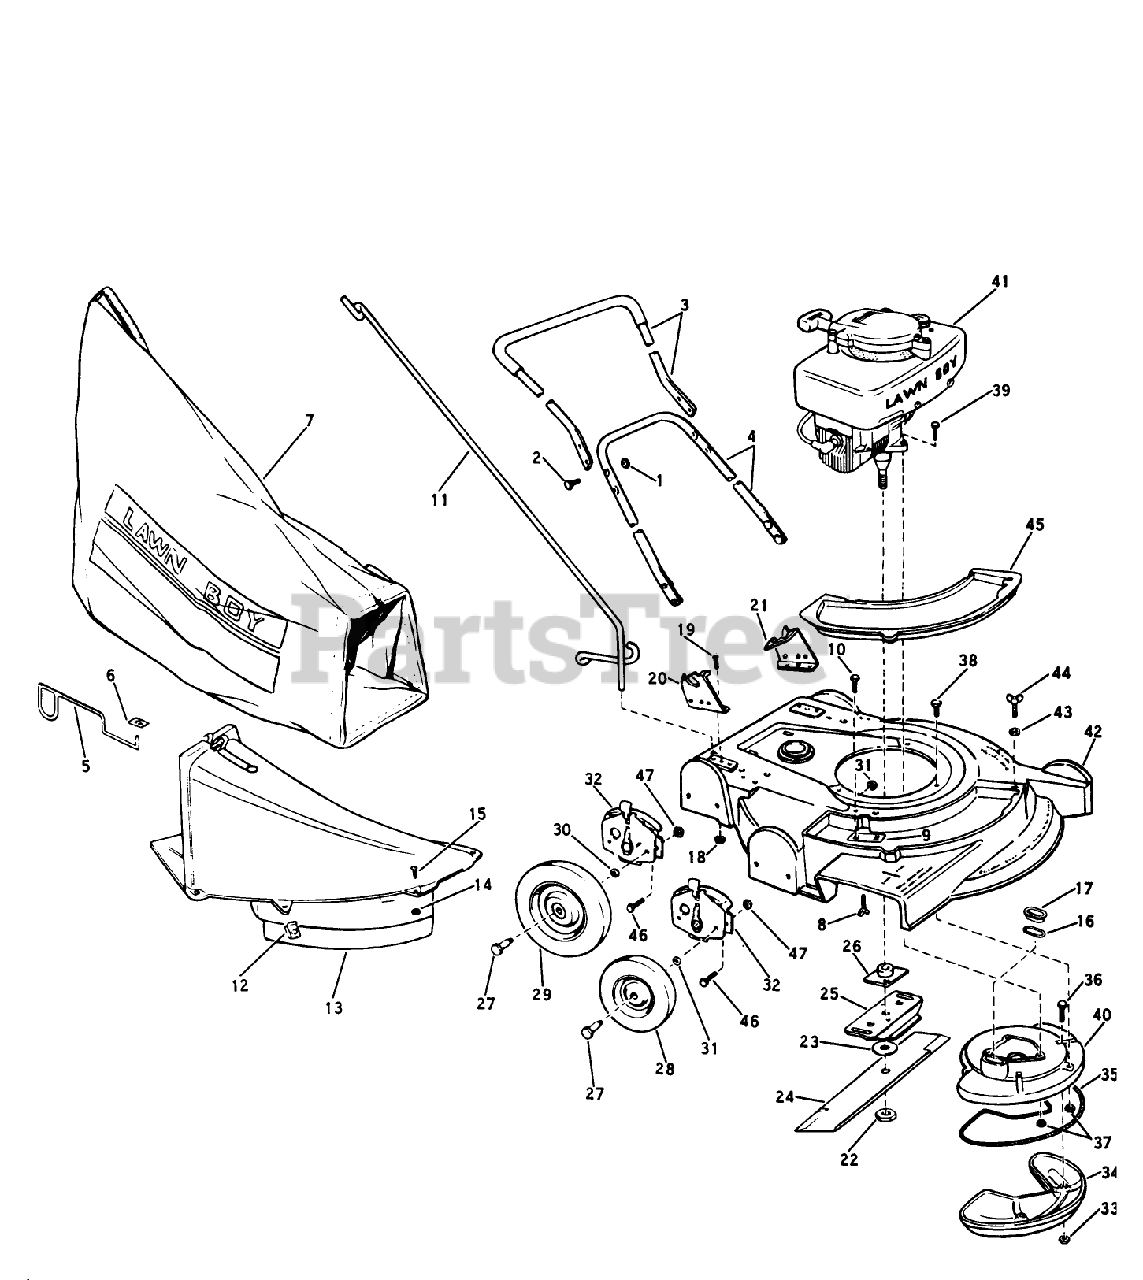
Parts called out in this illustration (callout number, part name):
3	Handle Grip Assy. Top
7	89802 LB WHOLE GOODS
12	SPEED NUT ARDEN
13	Chute Skirt Assembly (Includes Hardware)
16	GASKET S
22	NUT-BLADE
26	PLATE AND COLLAR ASM
27	BOLT WHEEL
30	WASHER WROUGHT
33	LOCKNUT E
41	Engine-Model C-18
